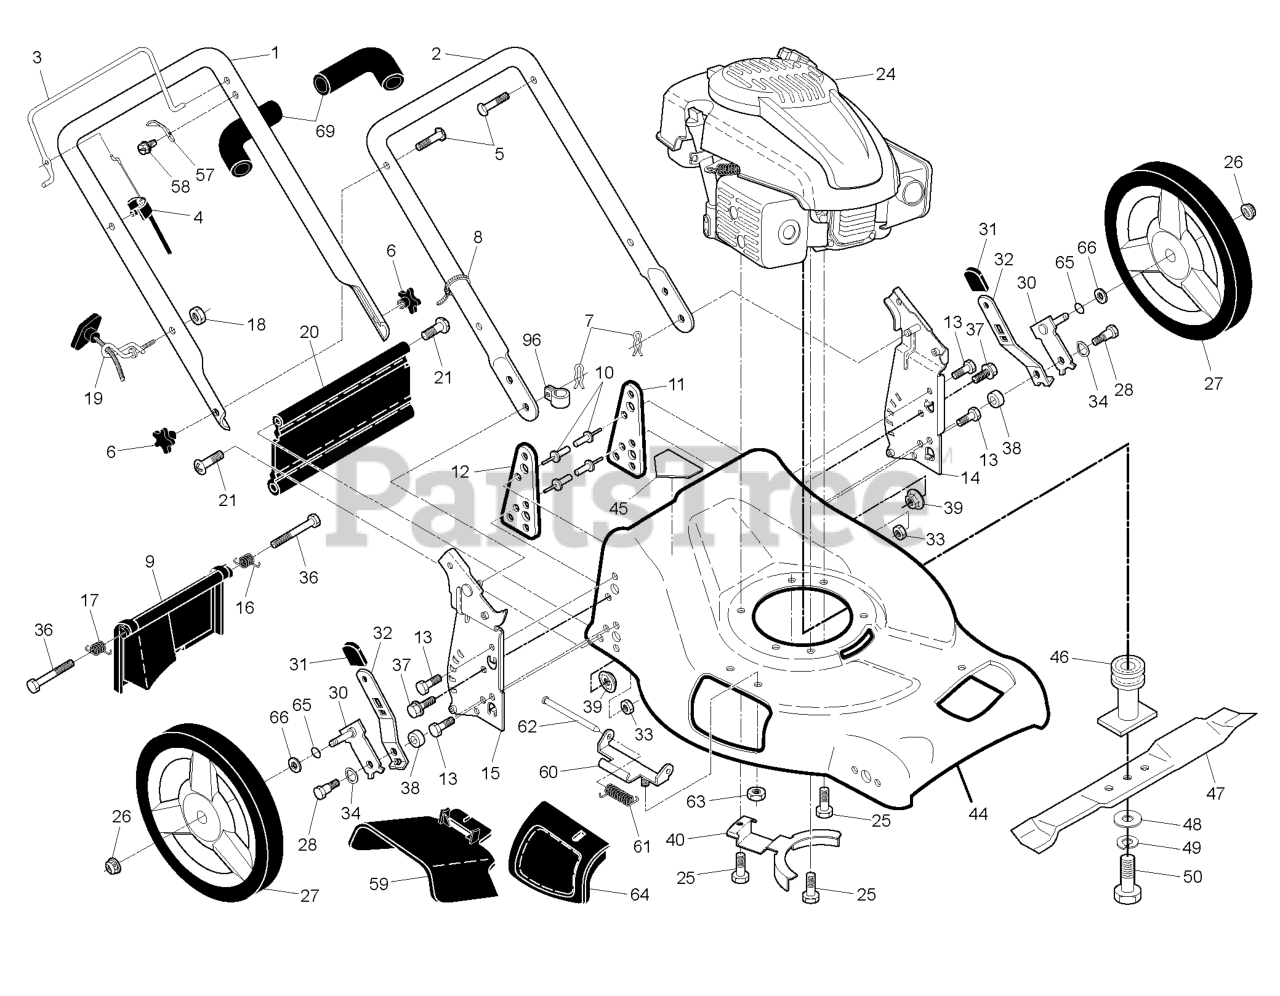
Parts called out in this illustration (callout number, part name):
1	HANDLE.ASM.GRY.W/GRIP
2	LOWER HANDLE
3	BAIL.DSTRT.AW.CREAS.ORAN
4	RP CABLE.MZR.54.10.SNAP.IN.RT
5	BOLT, HANDLE 5/16-18X1.75
6	KNOB.HANDLE.PLASTIC.STAR.BLACK
7	HAIRPIN COTTER
8	TIE GUIDE
9	REAR DOOR ASSEMBLY
10	RIVET BLIND
11	SUPPORT BRACKET LH
12	BRACKET.SUPRT.RH.21.FWGD
13	SCREW 14-20 X 5/8
14	RP BRACKET.ASM.HNDL/HW.LT.21.
15	BRACKET.ASM.HNDL/HW.RT.21.PNT
16	SPRING.REAR.DOOR.EZ.21.LT
17	SPRING.REAR.DOOR.EZ.21.RT
18	NUT
19	RB GUIDE.ROPE.STD.BLK.ZIN WSL
20	SKIRT.REAR.21 FWGD.BLACK
21	HINGE SCREW
25	BOLT 3/8-16X1-1/8
26	NUT.HEX.FLANGE.3/8-16.LOCKNUT
27	BRACKET.KEEPER.BELT
28	SHOULDER BOLT 5/16-18
30	ARM.ASM.AXLE.REAR.5/9.POS.BZP
31	SELECTOR KNOB
32	SELECTOR SPRING
33	NUT.FLANGE.5/16
34	WASHER.CURVED.CYLINDRICAL
37	BOLT.FIN.HEX.5/16-18X3/4
38	SPACER.HEIGHT.ADJUSTER
39	NUT.71038.31-18.HEX.NYLOCK
40	BRACKET.KEEPER.BELT
44	HOUSING.21.FWD.ORANGE.WALK
45	DANGER DECAL
46	RP ADAPTER.BLADE.25MM.21F
47	BLADE.21.PUSH/RWGD/FWGD
48	WASHER,HARDEN
49	LOCKWASHER
50	SCREW, HEX HD 3/8-24 X 1-3/8
57	BRACKET UPSTOP
59	DEFLECTOR.CLIPPIN.21.FGD
60	BRACKET.ASM.HINGE.21.FWGD.
61	SPRING.TORSION
62	ROD.HINGE.21
63	LOCKNUT.NYLOC.1/4-20
64	DOOR.MULCH.21.REAR.FWGD
65	O-RING..070X.487.NEOPRENE
66	WASHER.FLAT.1/2
69	GRIP.HANDLE.FOAM.WIDE.(1 SIDE)
96	CLIP.CABLE.BLK
